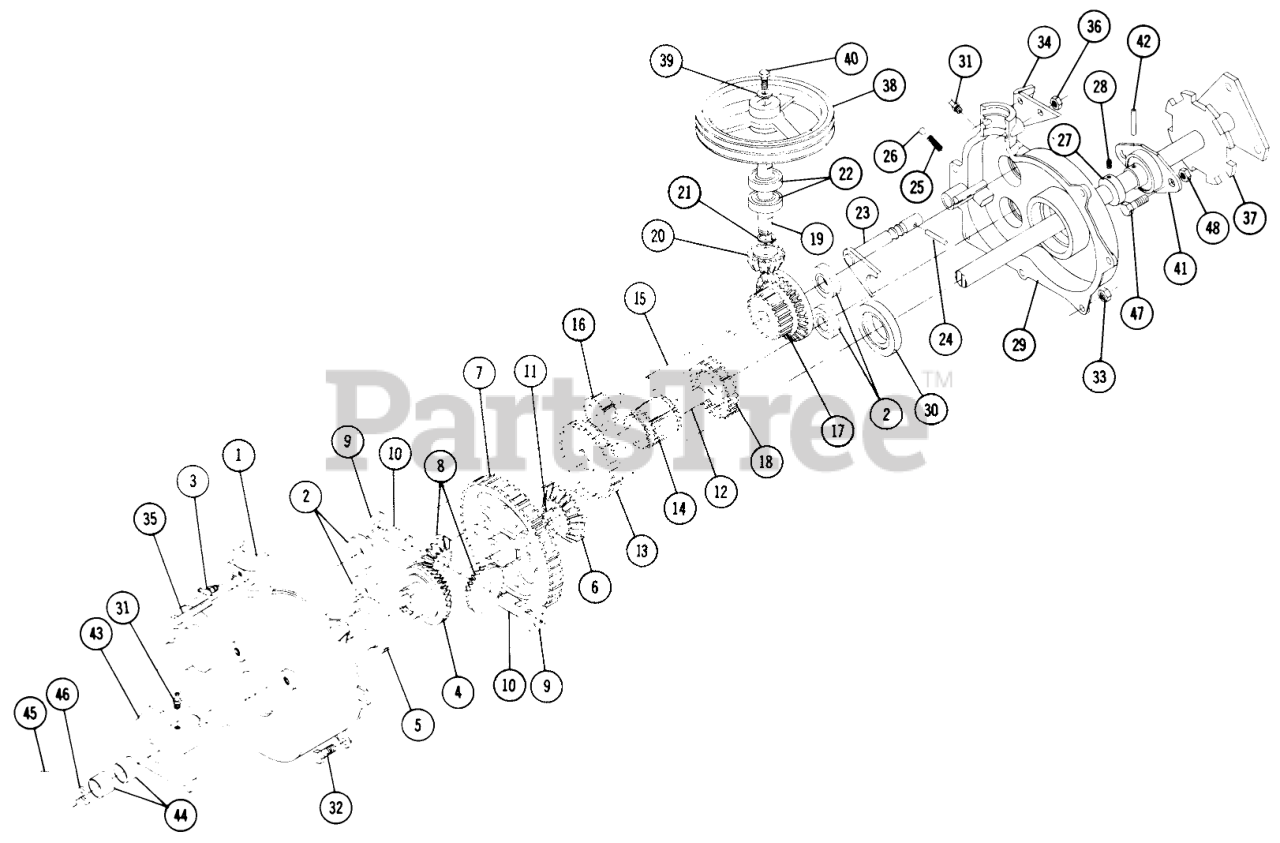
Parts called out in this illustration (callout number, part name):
3	FITTING-GREASE
11	WOODRUFF KEY
21	SNAP RING- 5/8 EXT
24	PIN-SPIROL
26	BALL-DETENT
28	Set Screw Nylok
32	Bolt, 5/16-18 X 7/8
33	Nut 5/16-18
34	Bracket-Shift Rod
35	Bolt Hex 5/6-18 X 2-1/2
36	Nut-Nylok
37	Ass-y. Axle
39	Washer
40	Bolt-Hex 5/16-18 x 5/8 Nylok
42	Spirol Pin
43	Ass-y Hub Flange
44	BUSHING-BRONZE
45	Bolt 3/8-16 x 3/4 Hex
46	WASHER
47	Bolt Hex 3/8-16 x 5/8
